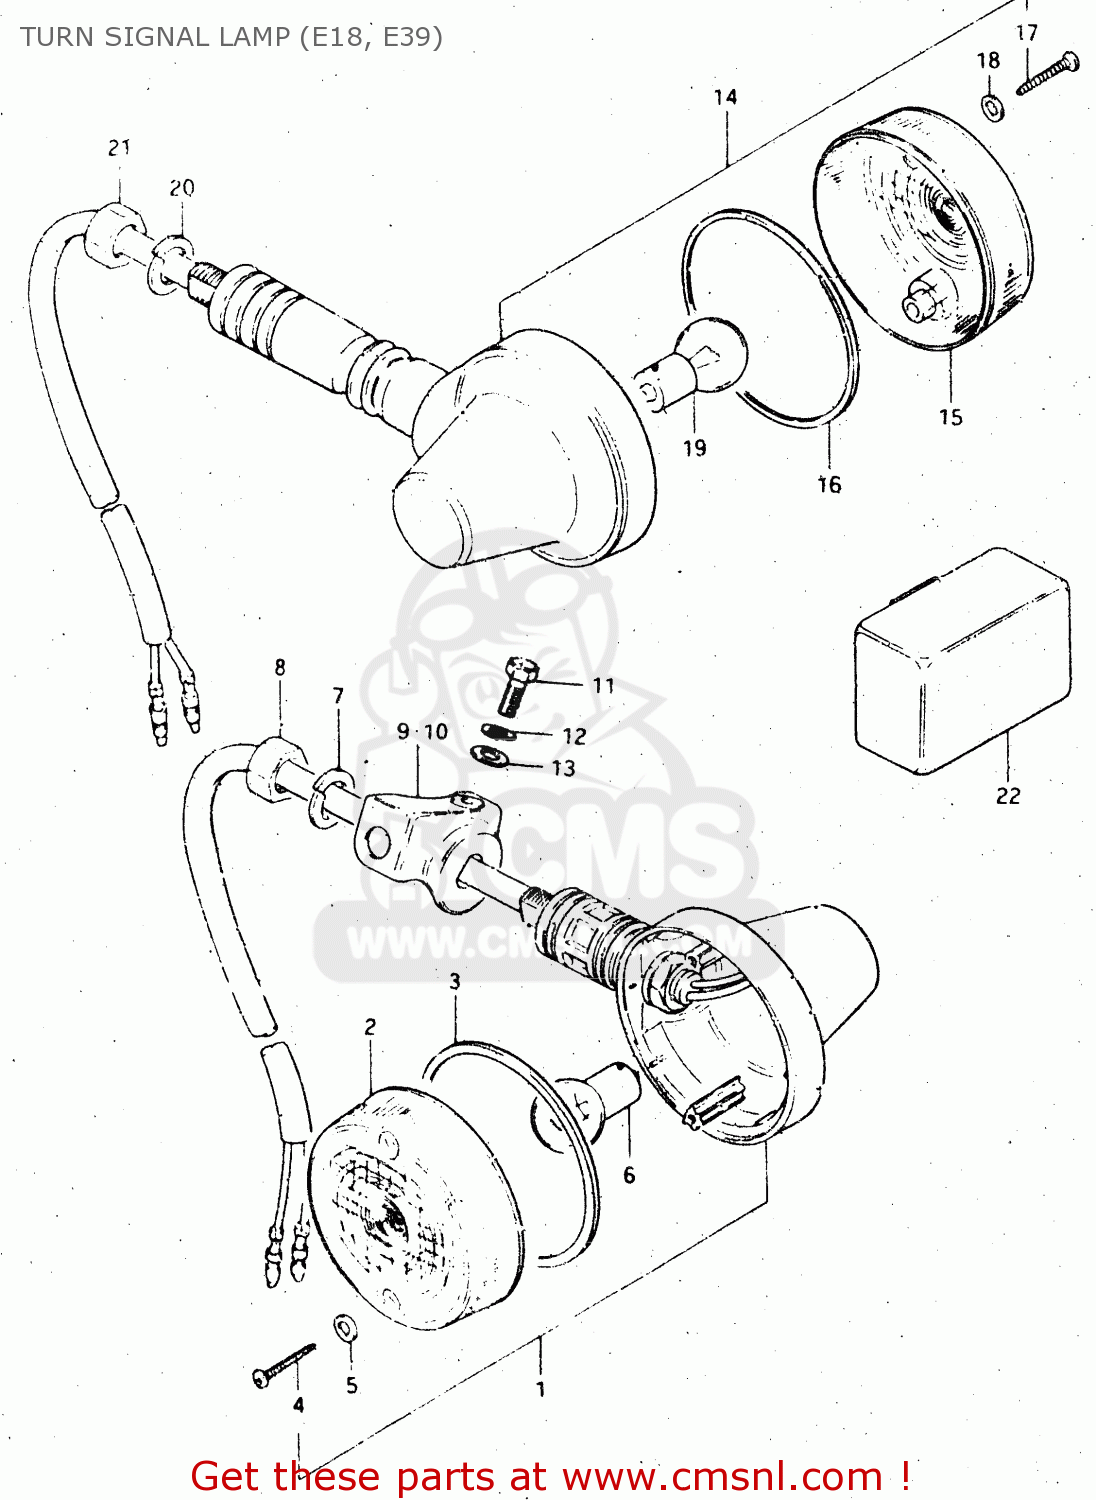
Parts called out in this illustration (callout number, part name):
1	LAMP, FRONT TURN SIGNAL
2	LENS
3	GASKET (NAS)
4	SCREW TAPP.
5	GASKET (NAS)
6	BULB (6V,21W)
7	WASHER
8	NUT 12MM
9	BRACKET,TURN SIGNAL LAMP
10	BRACKET,TURN SIGNAL LAMP
11	BOLT
12	LOCK WASHER
13	WASHER
14	LAMP, REAR TURN SIGNAL
15	LENS
16	GASKET (NAS)
17	SCREW TAPP.
18	GASKET (NAS)
19	BULB (6V,21W)
20	WASHER
21	NUT 12MM
22	RELAY, TURN SIGNAL
